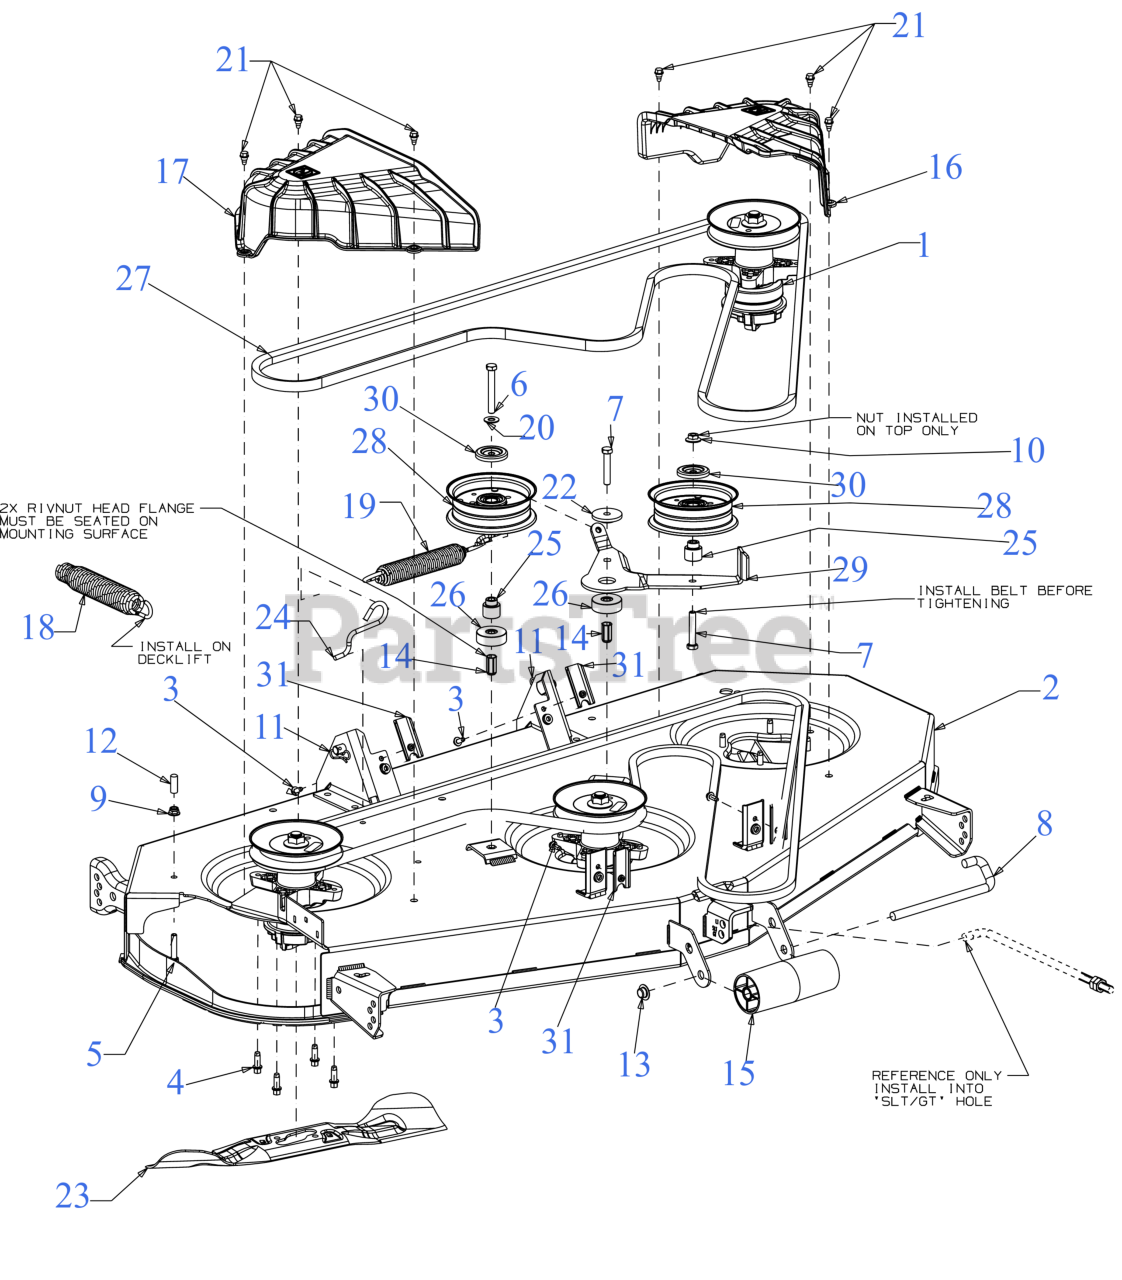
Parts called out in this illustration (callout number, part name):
1	BLADE SPINDLE ASSEMBLY
2	54" FAB FLAT TOP DECK SHELL
3	SCREW M6-1 x .625
4	SCREW 5/16-18 x .875
5	SCREW 5/16-18 x 1.5 LG
6	SCREW 3/8-16 x 2.75 GR5
7	SCREW 3/8-16 x 2.0 GR 8
8	ROLLER PIN 1/2 x 7.31
9	FLANGE LOCK NUT 5/16-18
10	FLANGE LOCK NUT
11	BOW TIE COTTER PIN
14	NUT RIVET 3/8-16
16	SPINDLE COVER (LH)
17	SPINDLE COVER (RH)
18	LIFT ASSIST SPRING (LARGE)
19	SPRING 1.25" DIA x 8.5" LONG
20	FLAT WASHER .401X.88
21	SHOULDER SCREW 1/4-20 x .50
22	SHOULDER SPACER
23	18.611" BLADE (2N1) (FASTATTACH)
23	54" FASTATTACH XTREME MULCH BLADE
23	54" LOW-LIFT SAND FASTATTACH BLADE
24	DECK SPRING HOOK
25	SHOULDER SPACER
26	SPACER .385ID x 1.75OD x .585THK
27	V-BELT B SEC x 139
27	Cub Cadet 54" DECK DRIVE BELT
28	IDLER PULLEY 4.50" DIA
29	IDLER PIVOT BRACKET
30	IDLER PULLEY CAP
